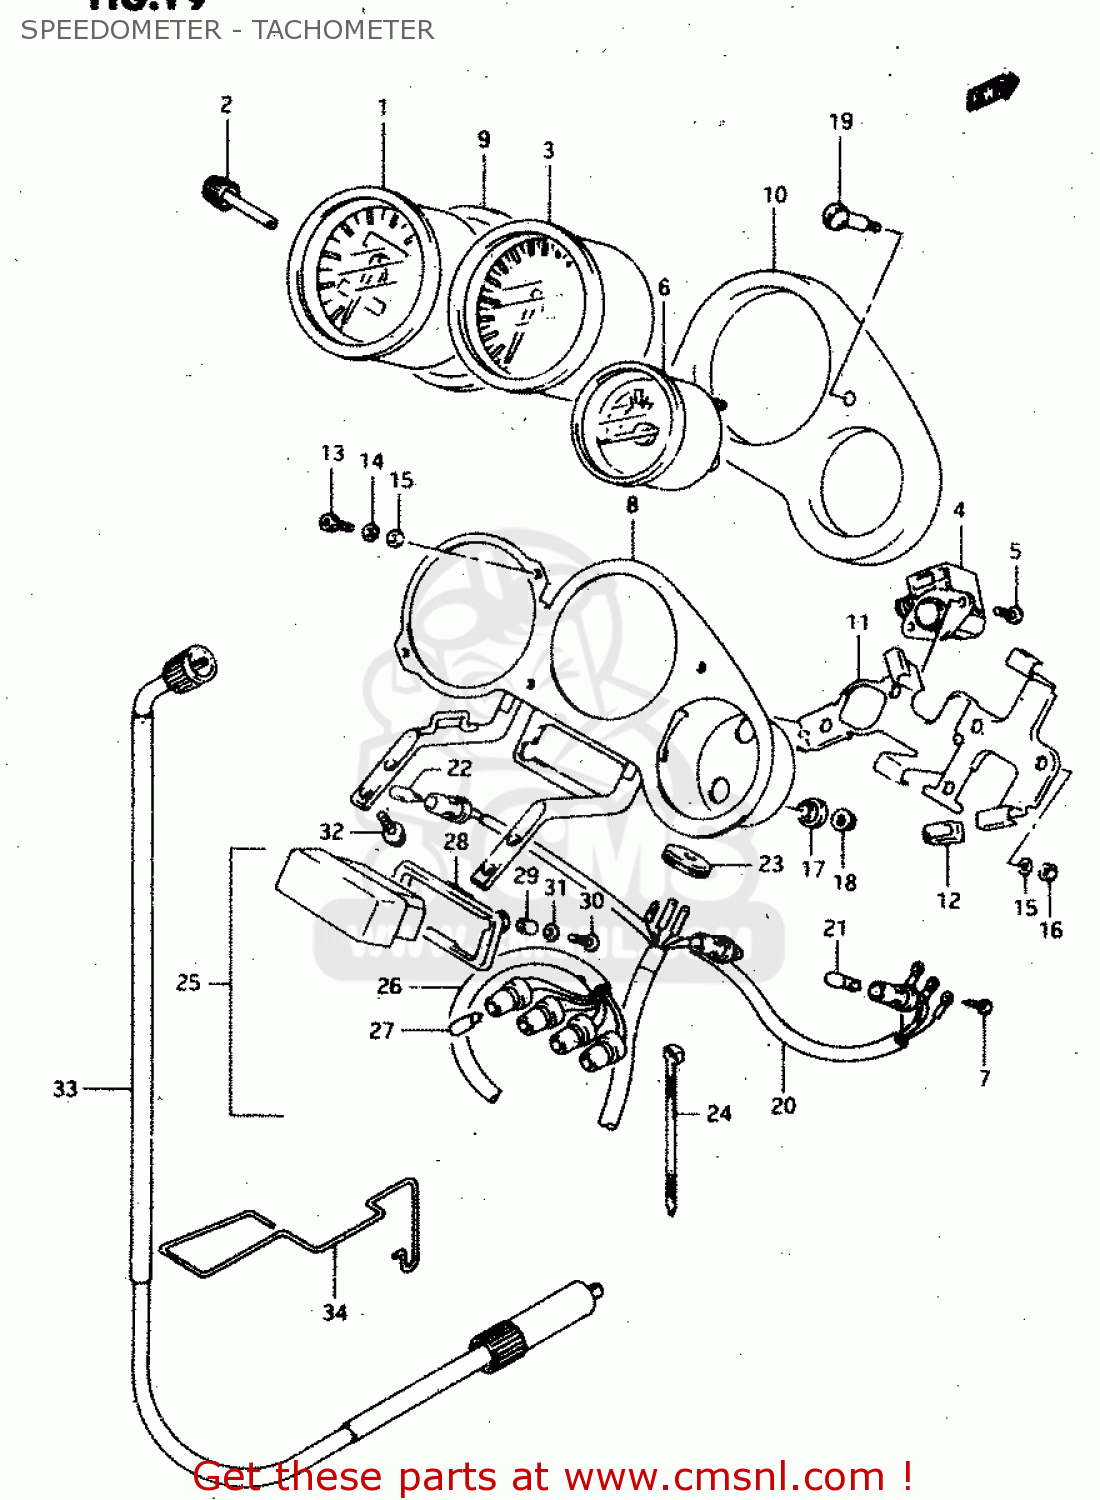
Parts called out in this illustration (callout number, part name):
1	SPEEDOMETER (KILO)
2	KNOB,TRIP
3	TACHOMETER
4	BOX,METER GEAR
5	SCREW
6	METER, TEMPERATURE
7	SCREW
8	BRACKET,SPEEDOMETER
9	CUSHION,SPEEDOMETER
10	CUSHION
11	BRACKET,SPEEDOMETER
12	CUSHION
13	SCREW
14	LOCK WASHER
15	WASHER,LOCK
16	NUT
17	CUSHION
18	NUT
19	SCREW
20	SOCKET
21	BULB(12V1.7W,WB372,T7)
22	BULB(12V3W,WB371,T7)
23	GROMMET
24	CLAMP
25	BOX ASSY, PILOT LAMP
26	SOCKET
27	BULB(13.5V,2W,A7427)
28	HOLDER, PILOT BOX
29	SPACER(4.5X6.5X9)
30	SCREW(3X16)
31	WASHER
32	BOLT
33	CABLE ASSY,SPEEDOMETER
34	GUIDE, SPEEDOMETER CABLE
